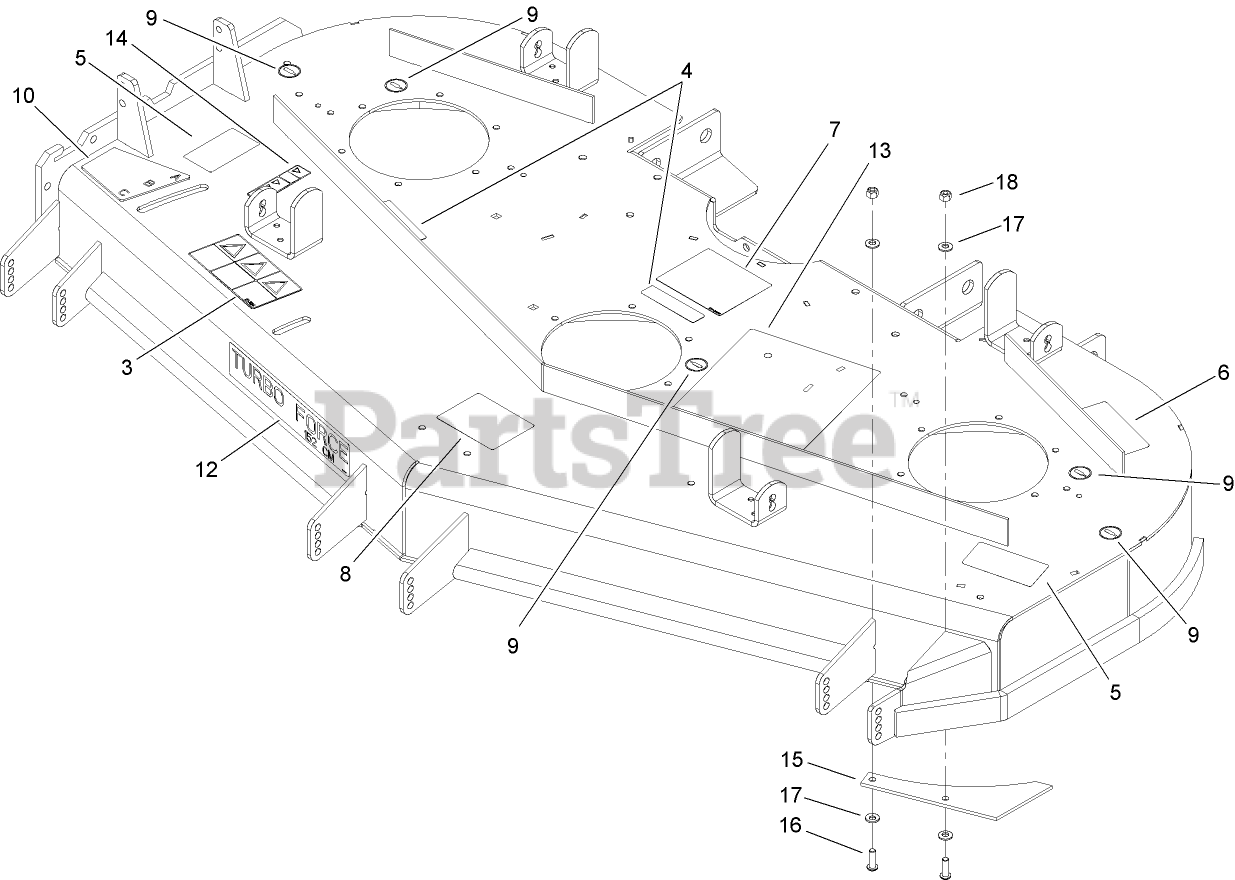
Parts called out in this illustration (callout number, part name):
3	DECAL-DANGER
4	DECAL-WARNING
5	DECAL-DANGER
6	DECAL-TORQUE, BLADE BOLT
7	DECAL-ROUTING, BELT
8	DECAL-ANTI SCALP
9	DECAL-GREASE
10	DECAL-ADJUSTMENT, BAFFLE
13	DECAL-SERVICE, CHECK
14	DECAL-WARNING, DEFLECTOR
15	PLATE-TURBO
16	SCREW-HSBH
17	WASHER-SPRING
18	NUT-LOCK, NI
